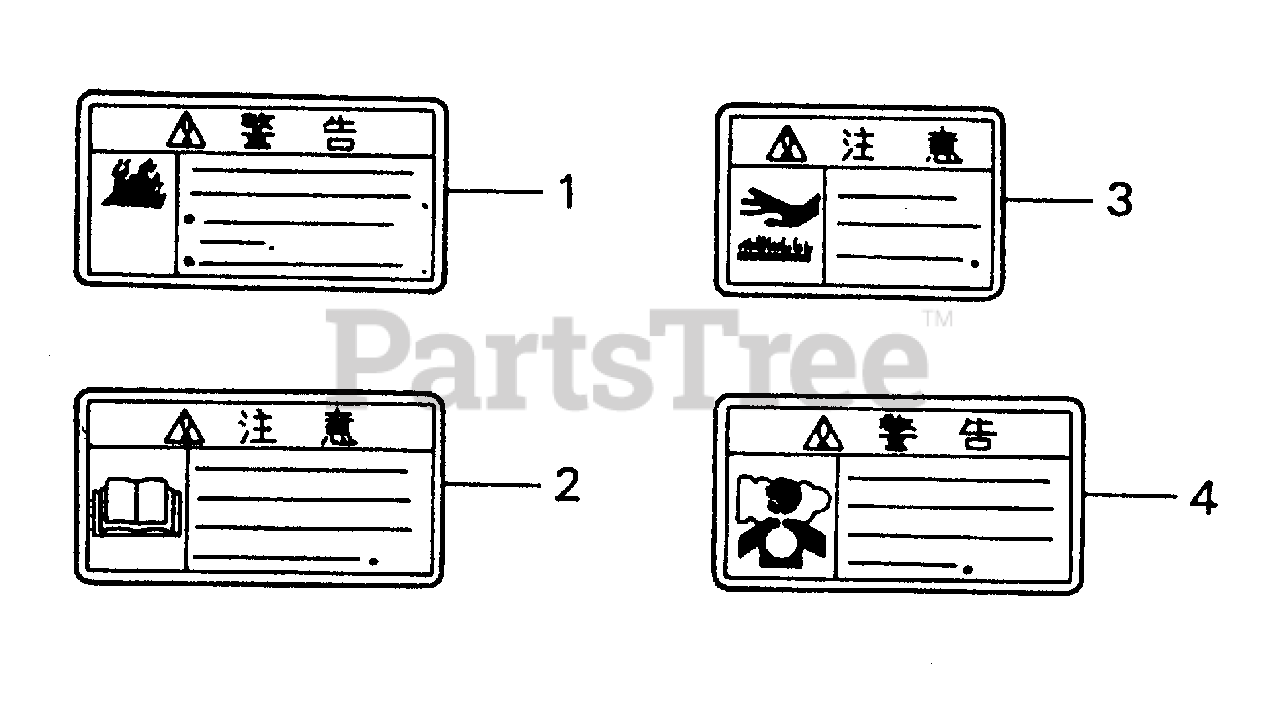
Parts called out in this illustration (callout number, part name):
1	MARK, FUEL WARNING
2	MARK, CAUTION (J)
3	MARK, HEAT CAUTION
4	MARK, EX. GAS WARNING
